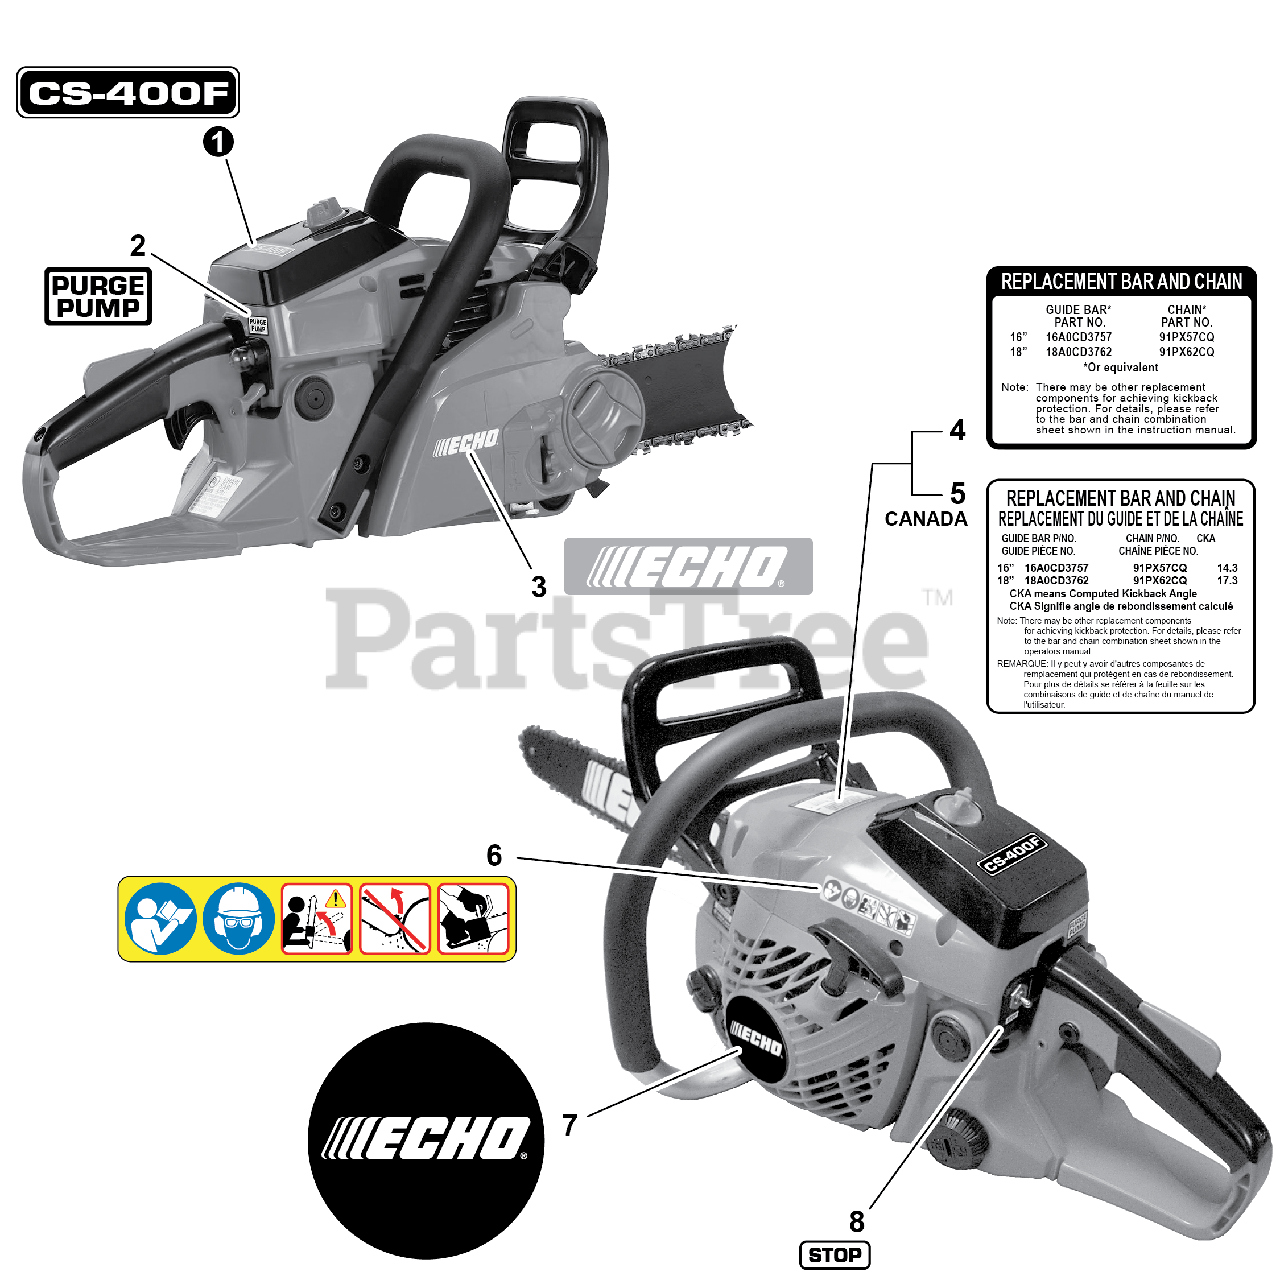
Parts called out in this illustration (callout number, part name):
1	LABEL - MODEL CS-400F
2	LABEL, PURGE PUMP
3	LABEL, ECHO
4	LABEL, BAR & CHAIN
5	LABEL, BAR & CHAIN - CANADA
6	LABEL, CAUTION
7	LABEL, ECHO
8	LABEL, STOP
